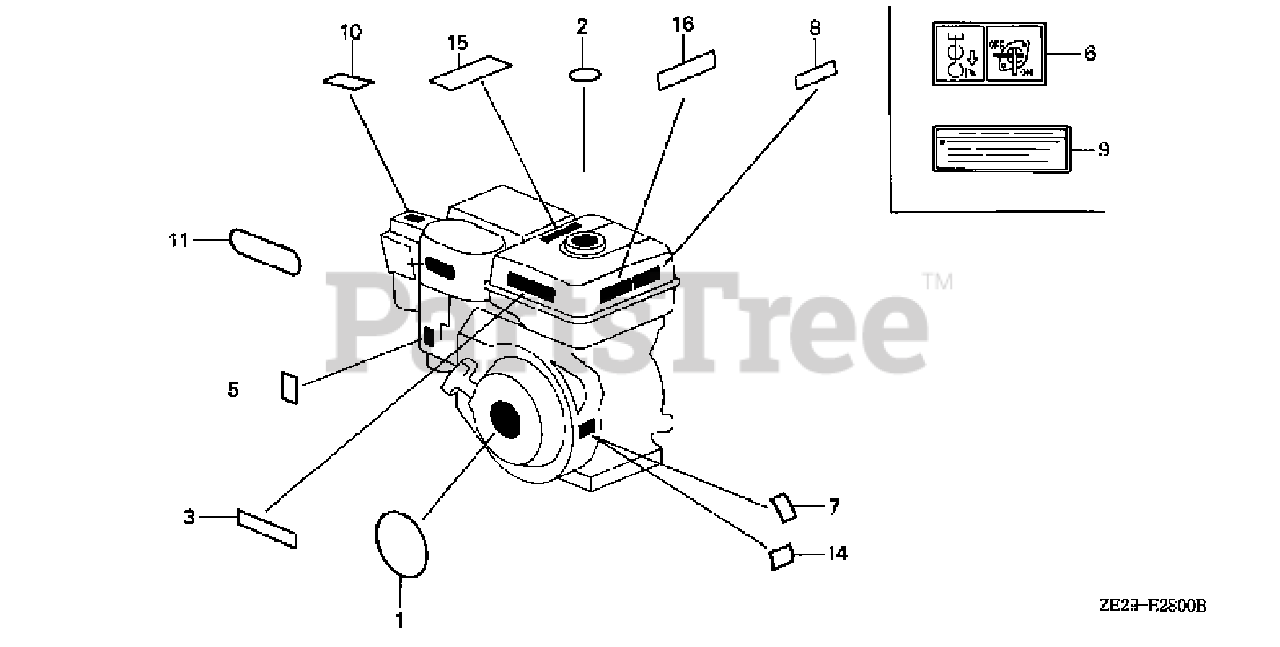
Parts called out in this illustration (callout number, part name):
1	EMBLEM (INTERNAL)
2	MARK, CAUTION (EXTERNAL)
3	LABEL, CAUTION
5	MARK, CHOKE (EXTERNAL)
8	MARK, OIL ALERT (GERMAN)
8	MARK, OIL ALERT (FRENCH)
15	LABEL, FUEL CAUTION
16	MARK, OIL ALERT (E)
